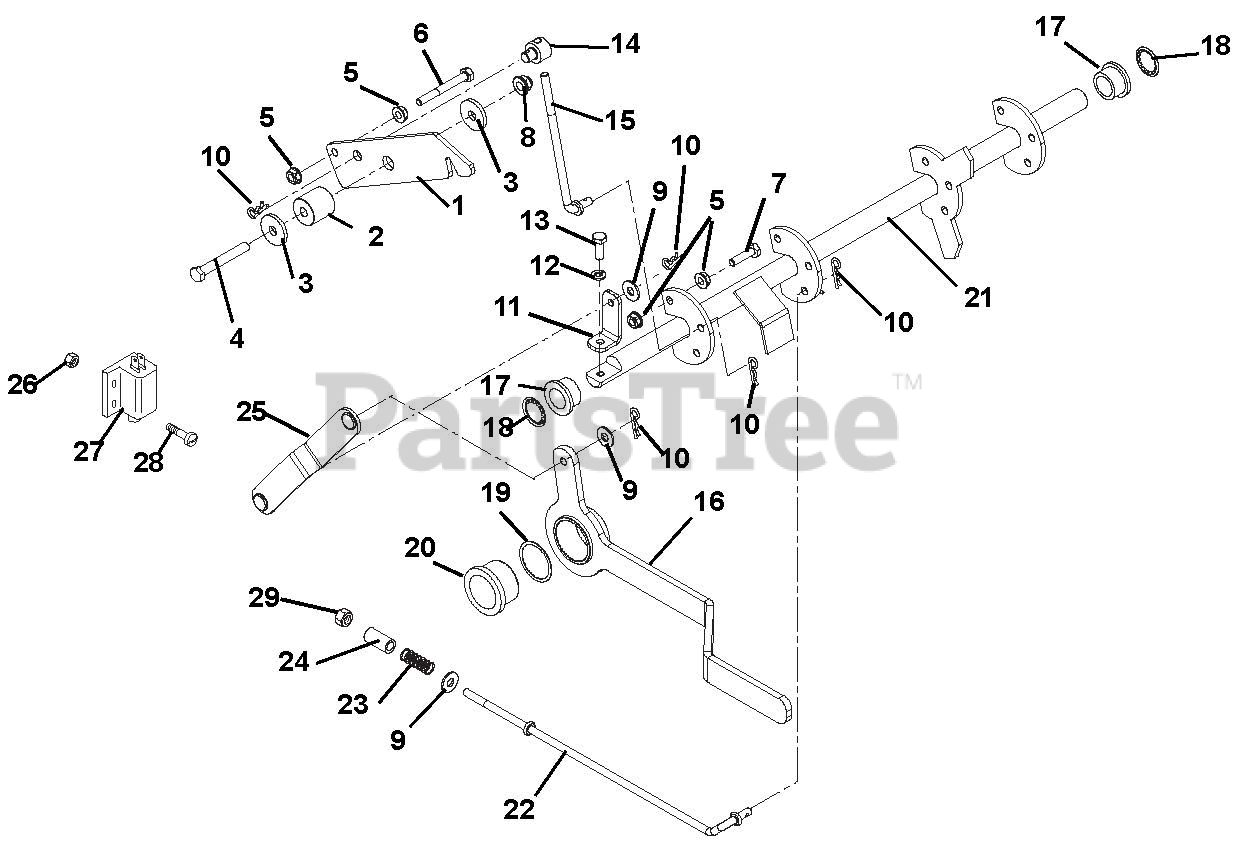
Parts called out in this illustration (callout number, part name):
1	LATCH, NEUTRAL
2	SPCR, FLG .32X.49X.192X1.00
3	WSHR-FL-STL .344X1.125X.135
4	@BLT-HEX .31-18X2.25 GR5 YWZC
5	@NUT-SPNLK-FLG .25-20 YWZC
6	@BLT-HEX .25-20X2.25 GR5 YWZC
7	@BLT-HEX .25-20X1.00 GR5 YWZC
8	@NUT-LK-NYL-FLG .31-18 YWZC
9	@WSHR-FL-STL.312X.734X.065 YWZ
10	PIN-HAIR INT .08X.18X1.18 YWZC
11	CRANK, PARKING BRAKE
12	@WSHR-LK .25X.062 REG YWZC
13	@BLT-HEX .25-20X.75 GR5 YWZC
14	TRUNNION, BRAKE .31-18 UNC
15	BRAKE LINK
16	WELDMENT, BRAKE LEVER
17	BSHG-FLG .750X1.000X.625X1.250
18	NUT, PUSH -.75" SHAFT
19	WASHER, NYLON 1.281X1.50X.03
20	BUSHING, PARKING BRAKE
21	WELDMENT, BRAKE SHAFT
22	BRAKE LINK
23	SG-COMP .045X.50X1.187
24	BSHG, SPCR .330X.500X1.01 PM
25	WELDMENT, BRAKE LINK
26	@NUT-LK-NYL 10-24 W/INSRT YWZC
27	SWITCH- DOUBLE POLE N.O./N.O.
28	@SCR-MCH 10-24X.75 HWH YWZC
29	@NUT-LK-NYL .250-20 YWZC
